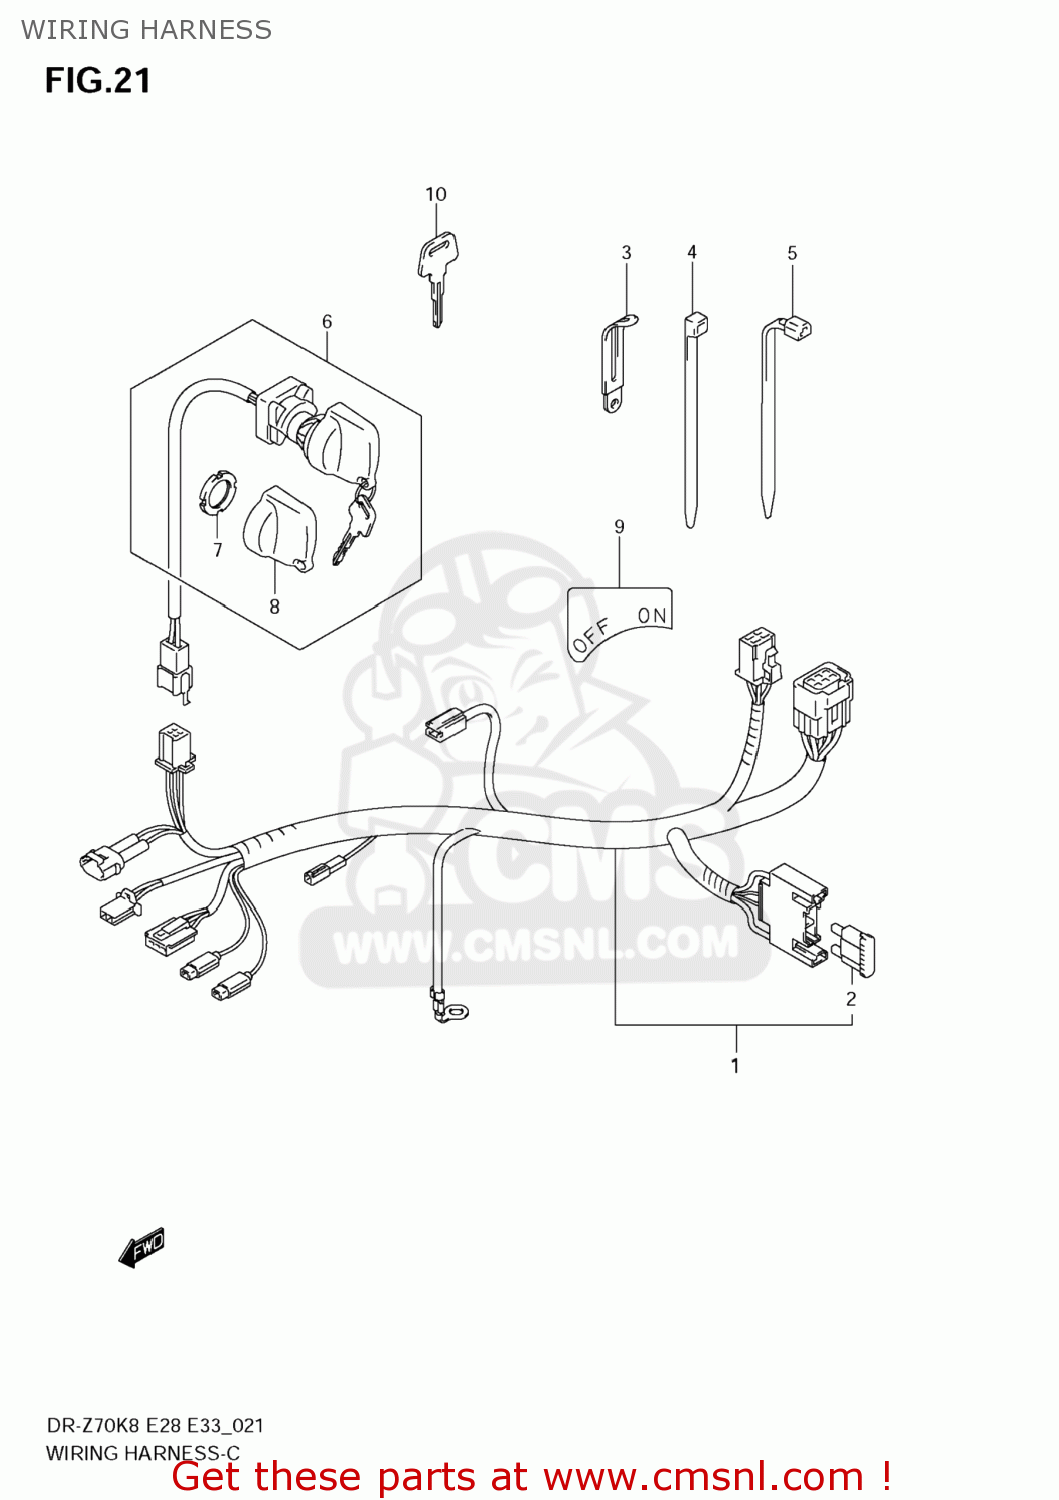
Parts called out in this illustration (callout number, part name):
1	HARNESS,WIRING
2	FUSE(10A)
3	CLAMP(L:45)
4	CLAMP(L:145)
5	CLAMP(L:235)
6	SWITCH ASSY,IGNITION
7	NUT,IGNITION SWITCH
8	MASCOT,KEY
9	PLATE CONTROL IDENTIFICATION
10	KEY,BLANK(TYPE:C)
